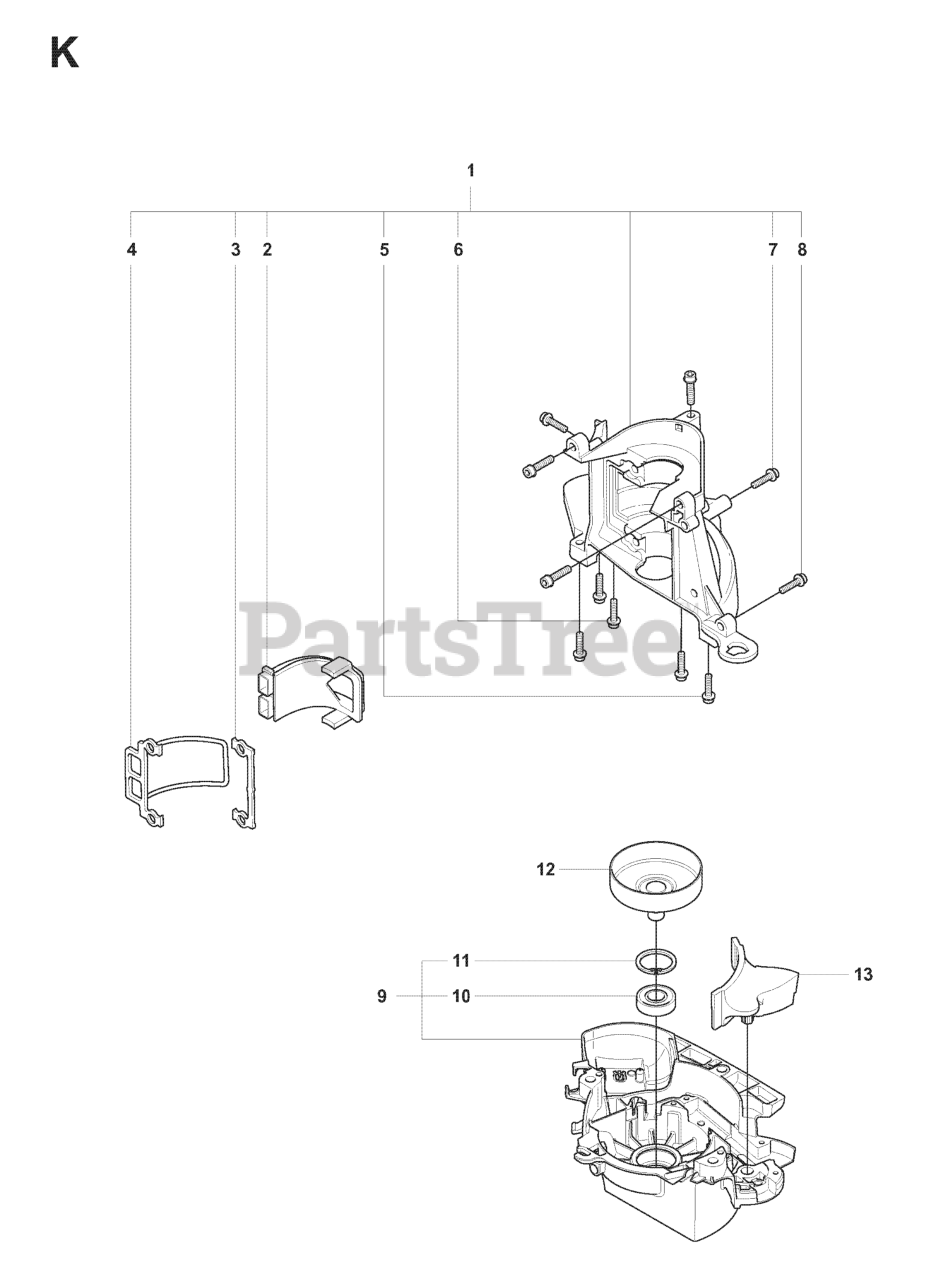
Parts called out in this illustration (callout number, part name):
1	CRANKCASE
11	RETAINING RING
12	CLUTCH DRUM
